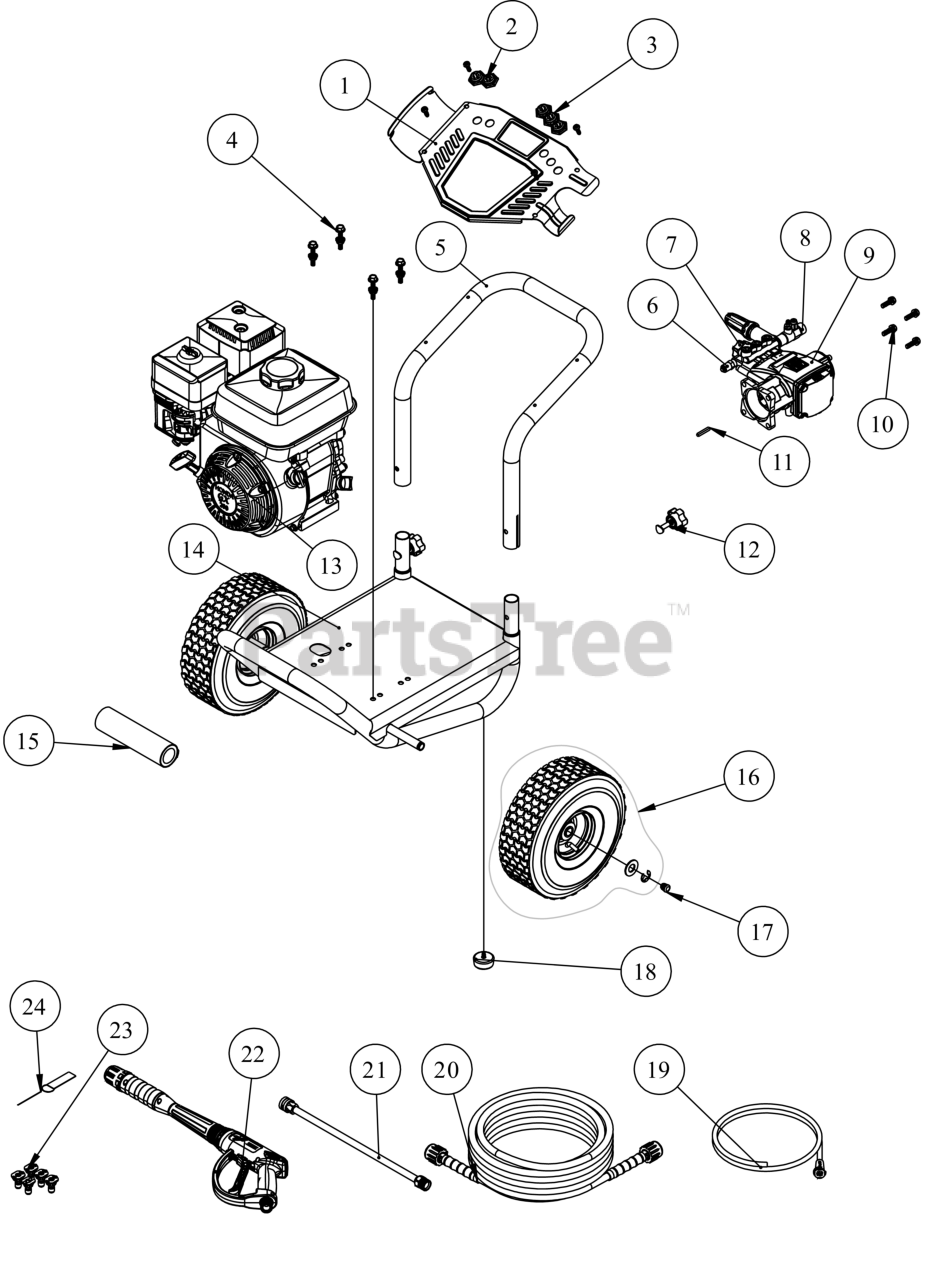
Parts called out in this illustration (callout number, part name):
1	DASHBOARD SVC ASSY
2	HOLDER-NOZZLE 2 PC
3	HOLDER-NOZZLE 3 PC
4	MOUNTING KIT: ENGINE
5	HANDLE, CUB YELLOW
6	VALVE-THERMAL RELIEF
7	WATER INLET KIT C31
8	FITTING KIT-OUTLET
9	PUMP, C32 SERIES, H-TRI
10	HARDWARE KIT: PUMP MOUNTING
11	SHAFT KEY (3/16x3/16x1.25)
12	KNOB-HANDLE MTG
13	ENGINE, HONDA RED GX200
14	FRAME, BASE WELDMENT CUB CADET
15	GRIP-HANDLE
16	10" WHEEL (BEIGE)
17	CAP, PLASTIC, 5/8 HOLLOW AXLE
19	HOSE-SOAP W/FILTER
20	HOSE, MORFLEX 1/4" x 25' x 3100PSI M22 x M22
21	WAND-SPRAY GUN 16"
22	SPRAY GUN (3600PSI M22)
23	5 PIECE NOZZLE SET
24	TOOL-NOZZLE CLEANING
